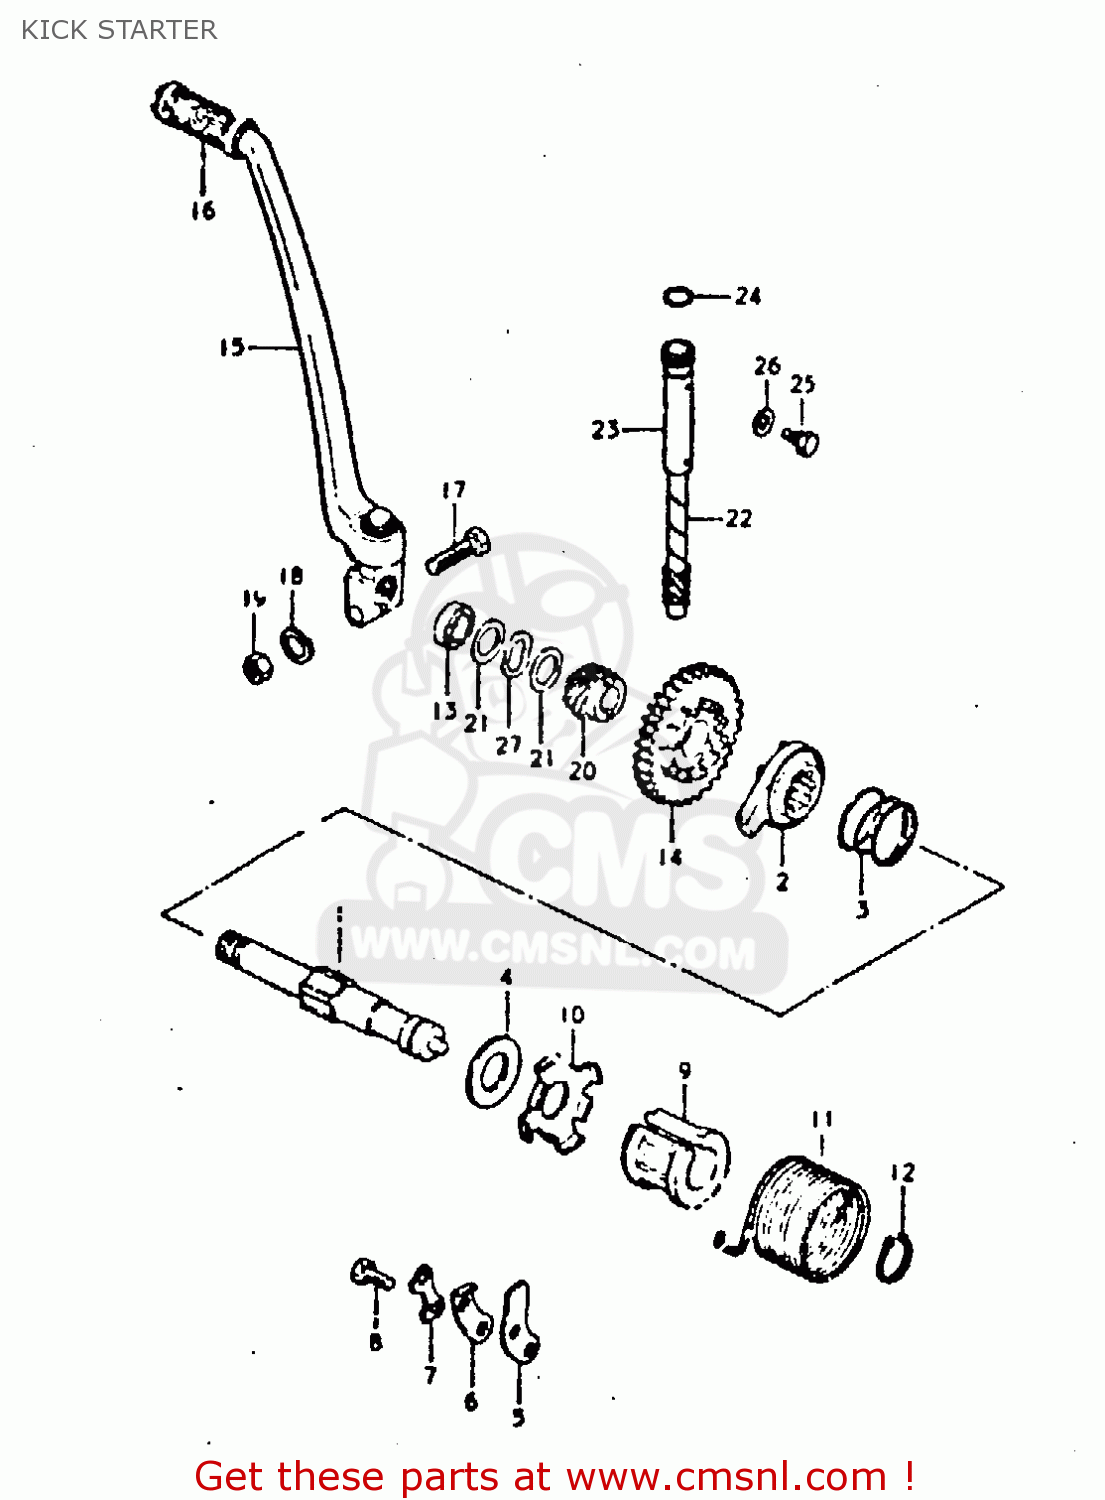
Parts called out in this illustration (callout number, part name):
1	SHAFT, KICK STARTER
2	STARTER,KICK
3	SPRING
4	WASHER
5	GUIDE,KICK STARTER
6	STOPPER,KICK STARTER
7	WASHER
8	BOLT, UPPER
9	GUIDE,KICK SHAFT SPRING
10	HOLDER,KICK SHAFT SPRING
11	SPRING
12	CIRCLIP
13	SEAL,OIL(16X24X5)
14	GEAR, KICK STARTER DRIVE
15	LEVER ASSY,KICK STARTER
16	RUBBER
17	BOLT,M10X1.25X
18	LOCK WASHER
19	NUT
20	GEAR, TACHOMETER DRIVE (NT:13)
21	WASHER
22	GEAR, TACHO. DRIVEN (NT:10)
23	SLEEVE,TACHOMETER DRIVE GEAR
24	O RING(D:1.3,ID:9.6)
25	BOLT
26	WASHER
27	WASHER
